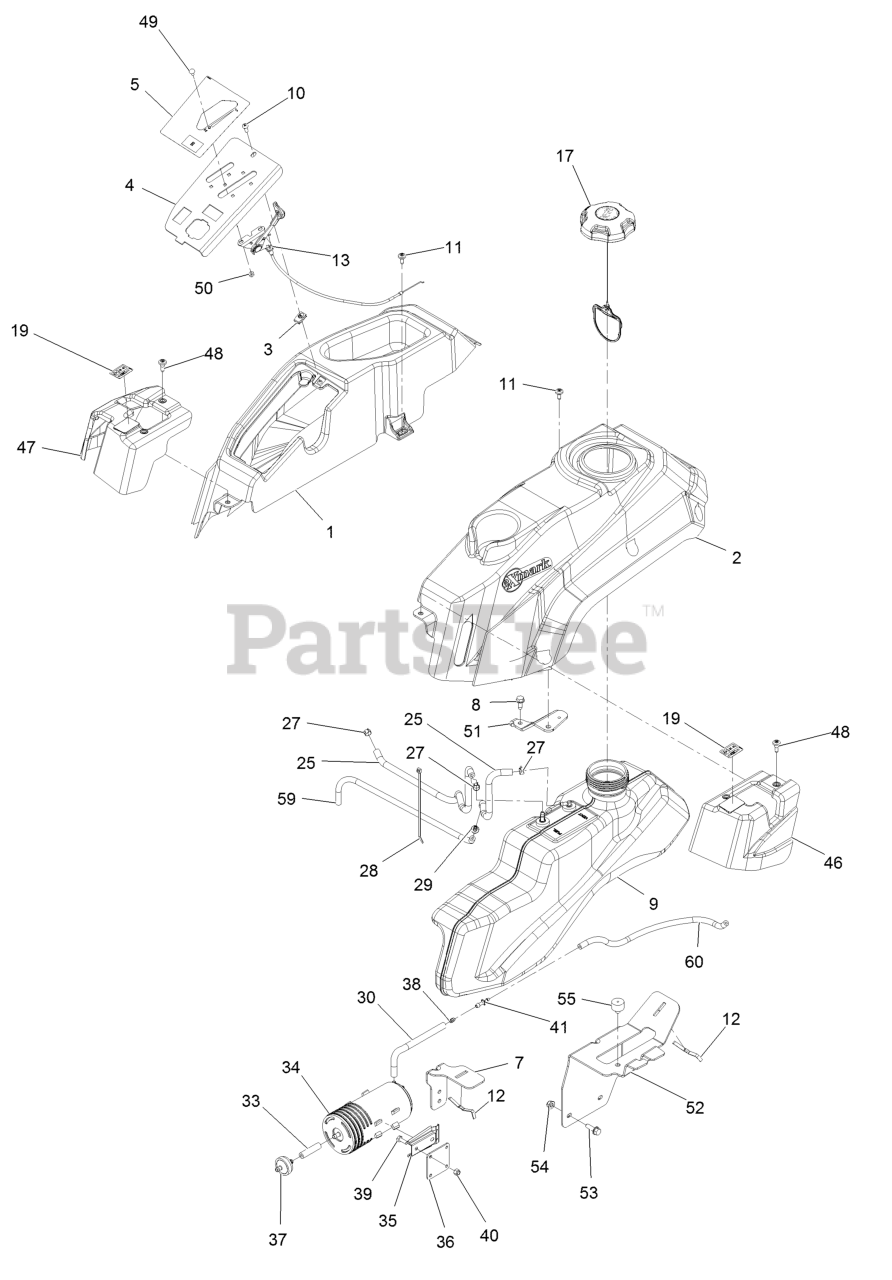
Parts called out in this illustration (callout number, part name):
1	Pod-RH, Narrow
2	Pod-LH, Narrow
3	Nut-Retainer-Panel 1/4-20
4	Panel-Control, Narrow
5	Decal-Control
7	Support-Tank [black]
8	Screw-HWH 5/16-18 X 3/4 Tf
9	Tank, Fuel
10	Screw-PPH 1/4-20 X 3/4
11	Screw-1/4-20 X 1/2 Tf Torx Plus
12	Spring
13	Cable Throttle Choke Control
17	Cap-Fuel, Ratcheting
19	Decal-Motion Control
25	Hose-Fuel Line 10 1/2"
25	Hose-Fuel Line 24"
27	Clamp-Hose
28	Tie-Cable
29	Adaptor-Orifice
30	Hose-Fuel
33	Hose-Fuel
34	Canister-Carbon, 800Cc
35	Bracket-Canister, Carbon
36	Plate-Adapter
37	Filter-Fuel, Inline
38	Cartridge-Valve, Check
39	Screw-HH 1/4-20 X 3/4
40	Nut-Nyloc 1/4-20
41	Fitting-Straight
46	Cover, Motion Control LH
47	Cover, Motion Control RH
48	Screw-Shoulder
49	Bolt-Carriage #10-24 X 1/2
50	Nut-Nyloc #10-24
51	Bracket-Clamp
52	Bracket-Support Tank
53	Screw-HH Flg 5/16-18 X 1
54	Nut-Nyloc 5/16-18 Flg
55	Bumper-Grommet
59	Hose-Fuel
60	Hose-Fuel
